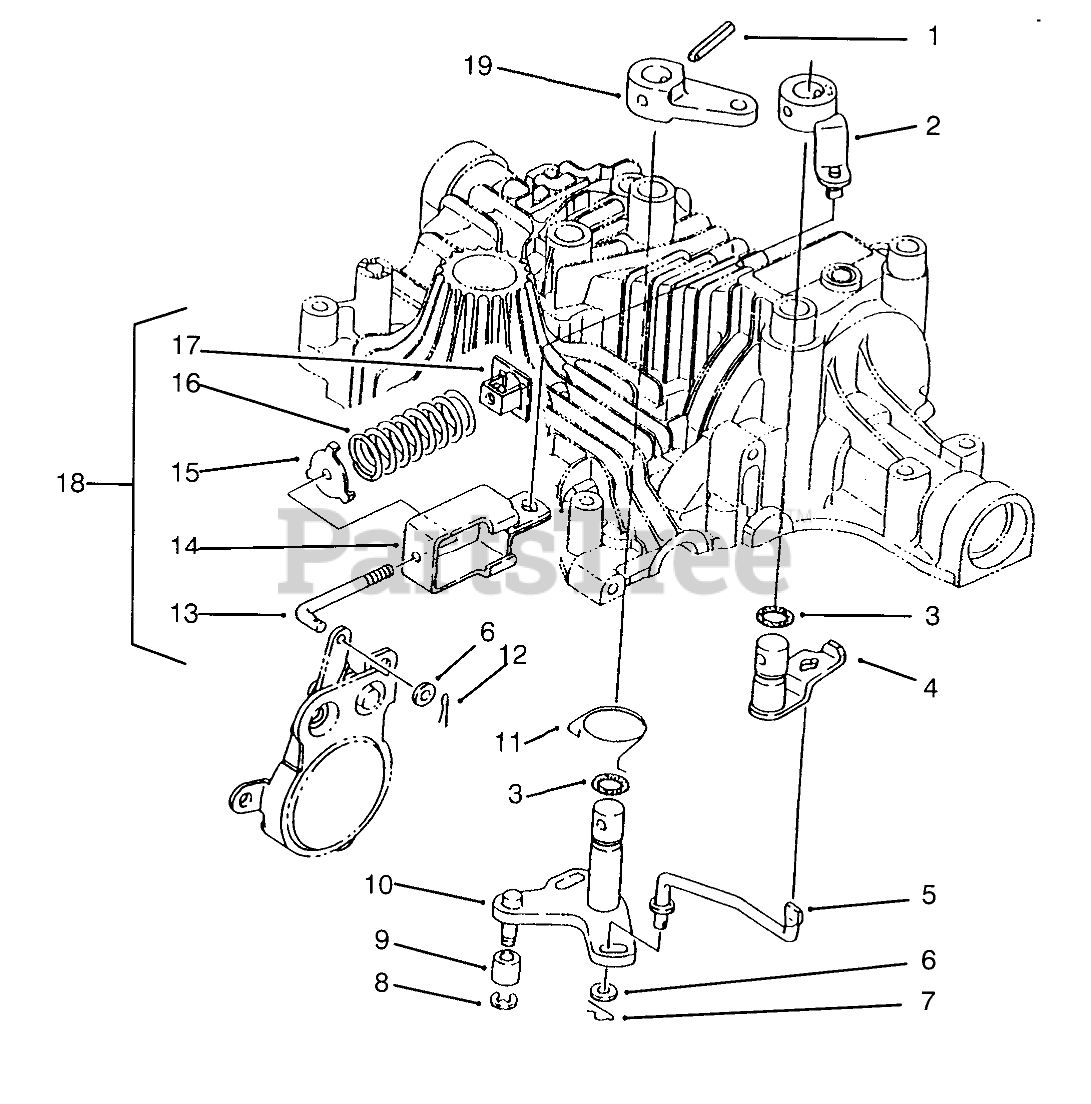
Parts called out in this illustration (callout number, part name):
1	PIN-ROLL
2	ARM-BRAKE B
3	O-RING
4	ARM-BRAKE A
5	ROD-BRAKE
6	WASHER
7	PIN - SNAP
9	BUSHING
10	SHAFT-BRAKE
11	RETURN-BRAKE
12	PIN-COTTER
13	ROD - ADJUSTER
14	HOLDER - SPRING
15	GUIDE - SPRING
16	SPRING
17	ADJUSTER
18	ROD ASM
19	ARM-BRAKE
